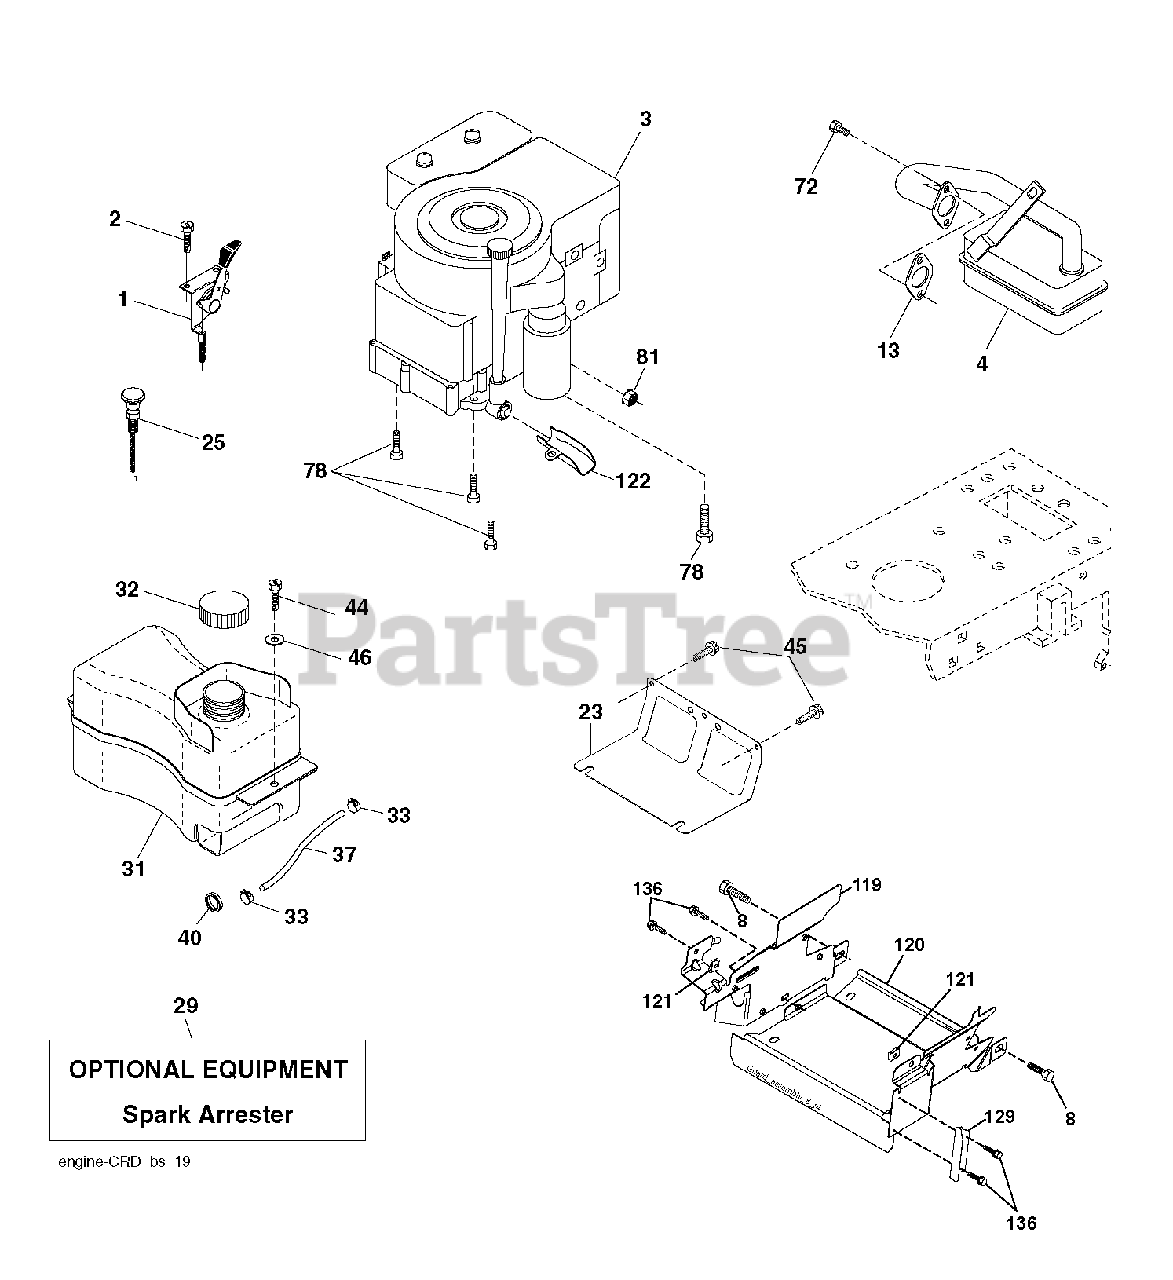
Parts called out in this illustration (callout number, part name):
1	CONTROL.THROTTLE/CHOKE.BLACK
2	SCREW
4	MUFFLER.LT.BRIGGS.14HP.IC/OHV
8	BOLT, 5/16-18 X 1 3/4
13	REPL BY 532 27 22-93
23	SHIELD.BROWNING.DBR.GUARD
25	KNOB.ERGO.EXTENDED.RED (1 2)
29	KIT.SPARK ARRESTOR 794945 B&S
32	CAP ASM.FUEL.2.25"FR.
33	HOSE CLAMP
37	LINE.FUEL.20
40	BUSHING.SNAP.NYL.BLK.
44	SCREW HEXWSHR 1/4-20X3/4
45	SCREW, 3/8-16X3/4
72	SCREW.SOCKET HD.5/16-1
78	SCREW.3/8-16
81	NUT
122	EXTENSION DRAIN OIL
136	SCREW.1/4-20X5/8
